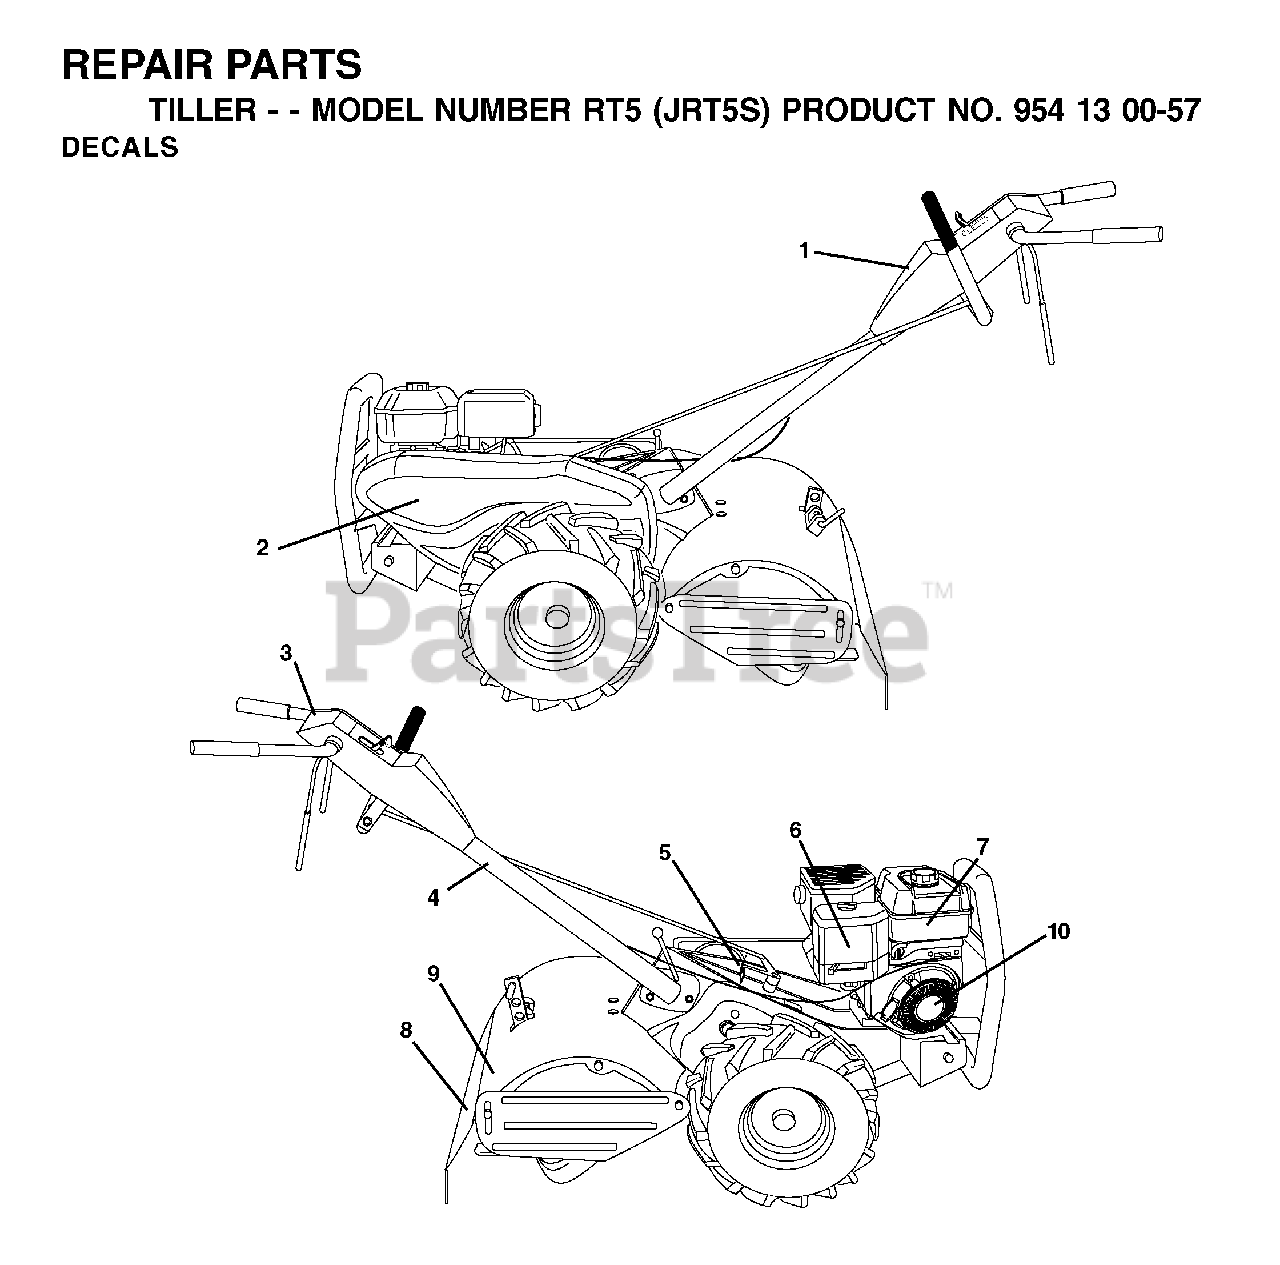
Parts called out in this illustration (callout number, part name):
5	DECAL.SHIFT.INDICATOR.TILLER
9	DECAL EUROPE STANDARD CE
10	DECAL.REWIND
